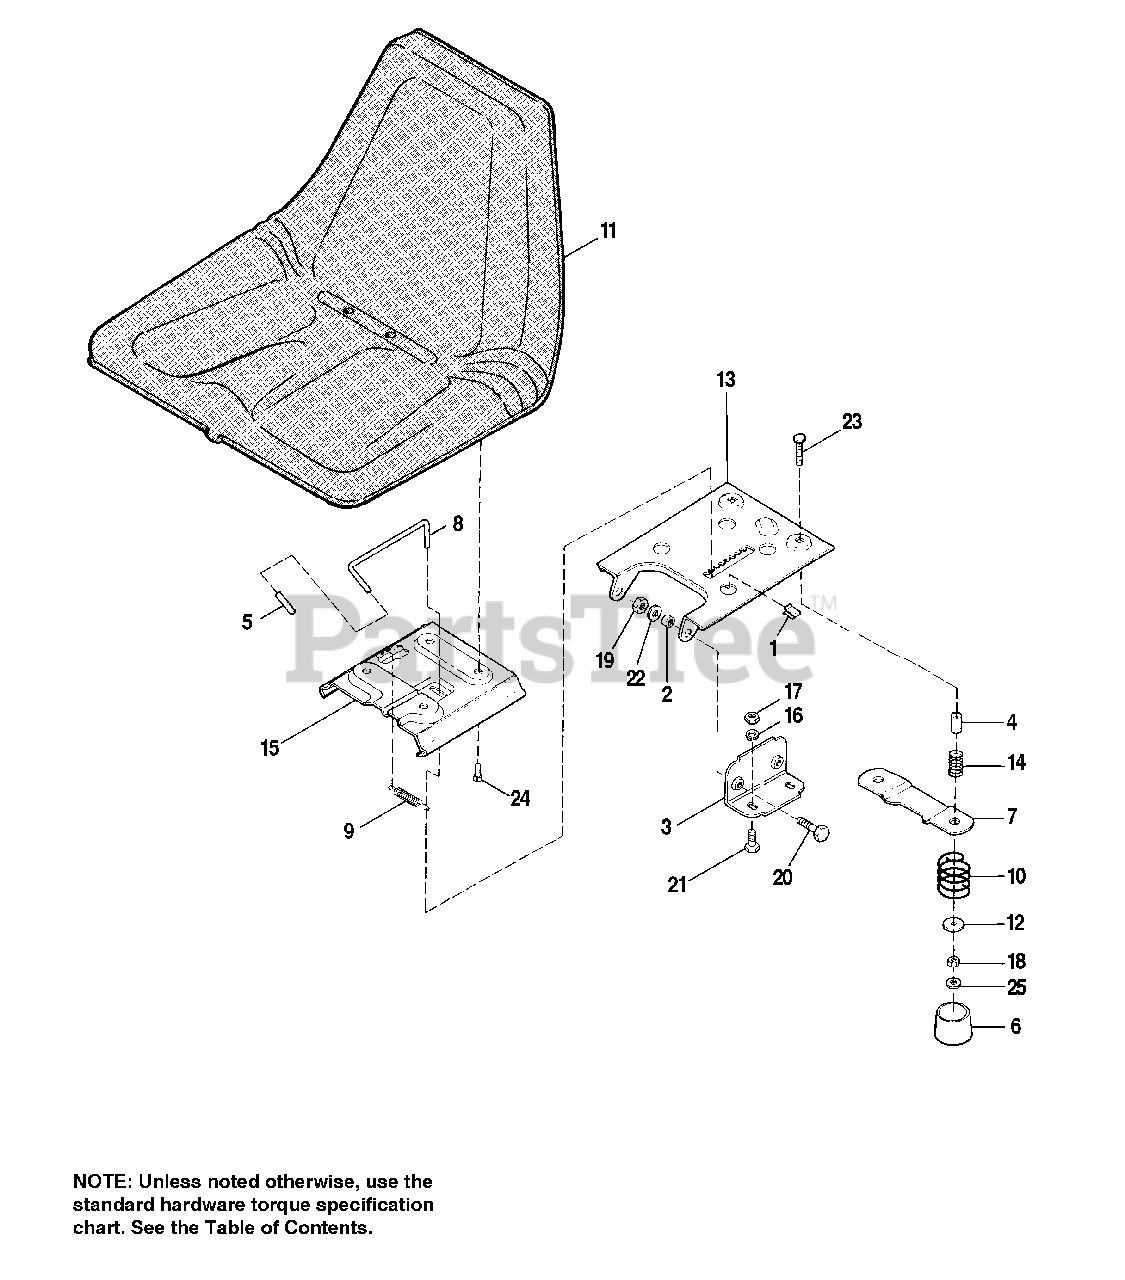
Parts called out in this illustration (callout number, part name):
1	CLIP, Speed
3	BRACKET, Seat, Suspension
5	HANDLE, Grip
6	COVER, Spring
7	PLATE, Switch
8	LEVER, Seat Release
10	SPRING, Compression, Seat
12	WASHER, Plain
13	SUPPORT, Seat, Pivot
14	SPRING, Compression
15	BRACKET, Seat Slide
16	LOCKWASHER, 5/16
17	NUT, Hex, Full, 5/16-18
18	NUT, Hex, Nylock, 5/16-18
19	NUT, Hex Hd., Nylock, 3/8-16
20	CAPSCREW, 3/8-16 x 1-1/4
21	CAPSCREW, Hex Hd., 5/16-18 x 3/4
22	WASHER, Plain 13/32
23	CARRIAGE BOLT, 5/16-18 x 2
24	BOLT, Hex, Whizlock, 5/16-18 x 5/8
25	WASHER, 1-1/32 x 1-7/8 x 1/16
